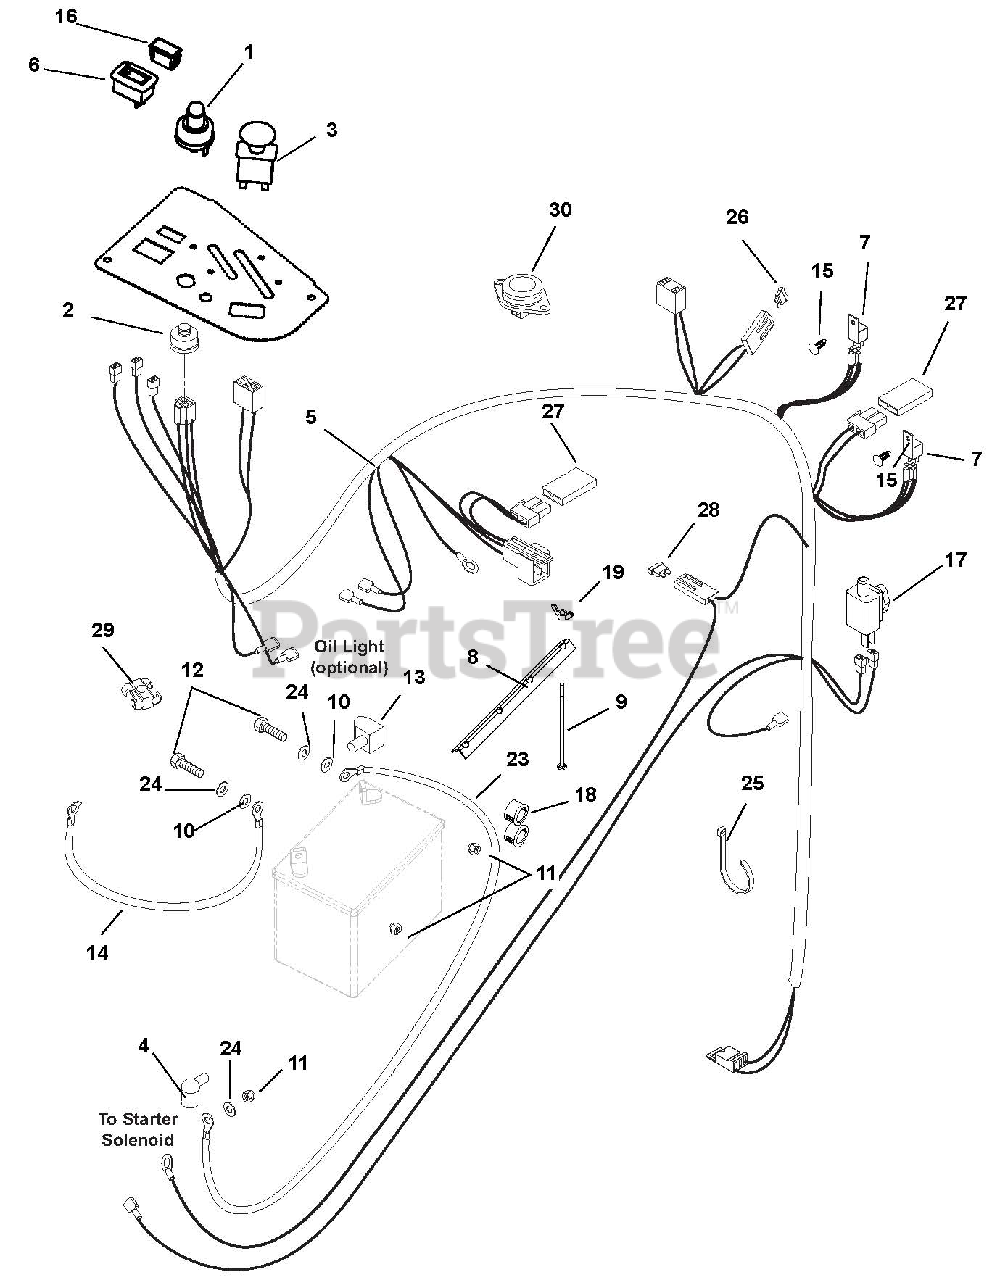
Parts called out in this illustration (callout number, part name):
1	Key, with Shield
2	Switch, Ignition
3	Switch, Clutch
4	Boot, Eyelet Terminal
5	Harness, CZ Remote SOL.
6	Hour Meter, with Maintenance
7	Relay, Sealed with Diode
8	Hold Down
9	Bolt, Round Head Square Neck .25-20 x 7.50
10	Washer, Flat Steel .281 x .620 x .065
11	Nut, Hex .25-20
12	Bolt, Hex .25-20 x .75 Grade 5
13	Insulator
14	Cable, Negative Battery
15	Rivet, .25 Nylon Panel
16	Plug, Hole .50 Diameter
17	Switch, Single Pole (N.O.) – Brake Switch
18	Bushing, Panel Snap .687 x .875 x .56
19	Nut, Locking Wing .25-20
20	Screw, Tapping .25-20 x .50 Hex Washer Head
21	Nut, Jam .31-24
22	Washer, Star Washer .31 x .078 Regular
23	Cable, Starter
24	Washer, Lock .25 x .062
25	Tie, Cable LG 5.50
26	Fuse 20AMP
27	Diode, Connector Shell
28	Fuse, 25 AMP
29	Clip,T,.31-.38
30	Switch, Seat
